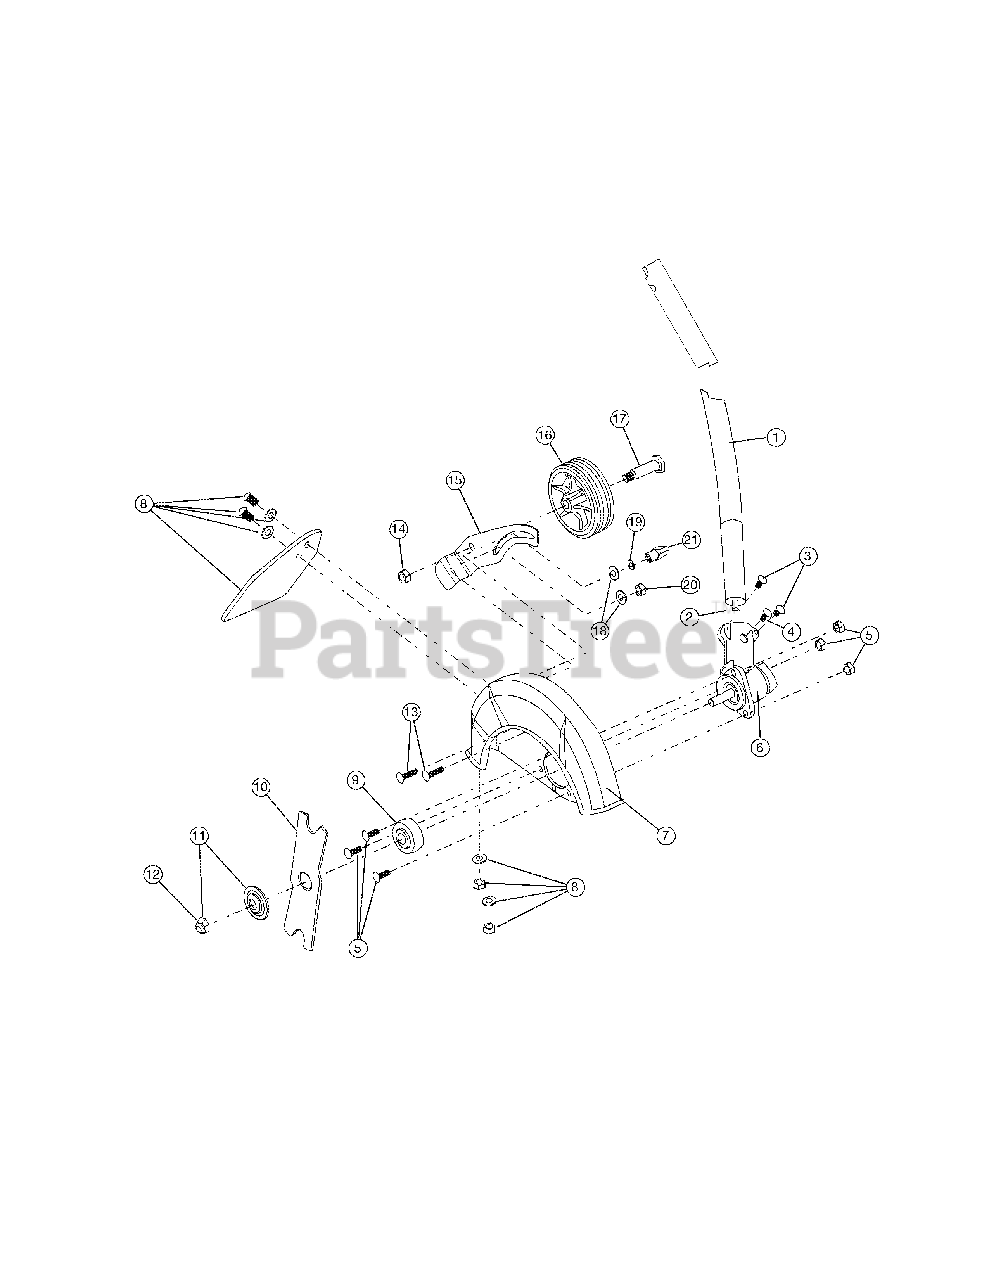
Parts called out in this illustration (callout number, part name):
1	Boom Assembly
2	Drive Shaft
3	Boom Mounting Hardware
4	Anti-Rotation Screw
5	Guard Mounting Hardware
6	Gearbox Assembly
7	Blade Guard
8	Deflector w/Hardware
9	Spacer
10	Blade
11	Blade Clamp Washer
12	Blade Retainer Nut
13	Wheel Bracket Mounting Bolt
14	Nut
15	Edger Guide
17	Shoulder Bolt
19	Washer
20	Nut
21	Edger Guide Knob
